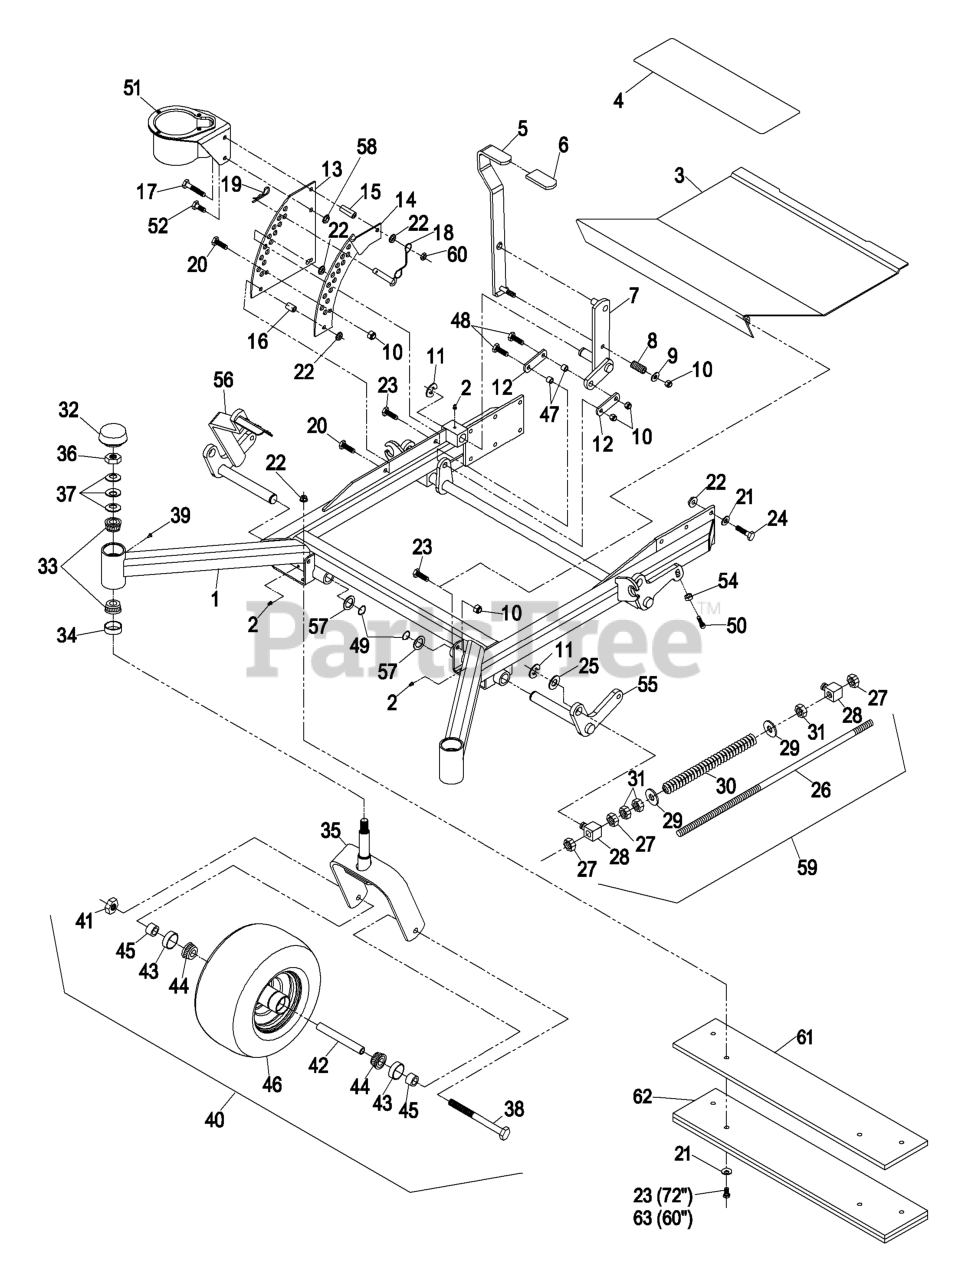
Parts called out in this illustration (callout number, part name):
2	FITTING-GREASE
4	PAD-ANTISKID
5	LIFT LEVER/GRIP ASM
6	GRIP-LEVER, LIFT
7	ARM-LIFT, DECK
8	SPRING-COMPRESSION
9	WASHER-FLAT
10	NUT-LOCK, NI
11	RING-RETAINING, EXT
12	ARM-LIFT, DECK
13	PLATE-LIFT, DECK
14	PLATE-LIFT, DECK
15	BUSHING-LEVER, LIFT
16	BUSHING-LEVER, LIFT
17	SCREW-HH
18	PIN-HITCH (W/LANYARD)
19	PIN-COTTER
20	SCREW-HH
21	WASHER-BELLEVILLE
22	NUT-HHF, WHIZ
23	SCREW-HH
24	SCREW-HH
25	WASHER-FLAT
26	ROD-LIFT, DECK
27	NUT-HEX
28	SWIVEL-DECK MOUNT, REAR
29	WASHER-FLAT
30	SPRING-SUPPORT, DECK
31	NUT-JAM
32	CAP-GREASE
33	Cone-Bearing Tapered Roller
34	SEAL-GREASE
36	NUT-LOCK, NI
37	WASHER-BELLVILLE
38	SCREW-HH
41	NUT-LOCK, NI
42	SPACER-CASTER, FRONT
43	SEAL-CASTER
44	BEARING-CONE, TAPERED ROLLER
45	SPACER-BEARING
47	BUSHING
48	SCREW-HH
49	RING-RETAINING
50	SCREW-HSH
52	SCREW-HH
54	NUT-JAM
55	WLD, FRONT LIFT SHAFT - L
56	WLD, FRONT LIFT W/ LEVER
57	WASHER-SPACER
59	FRONT FRAME SPRING ASM
62	Weight Bar, (60")
63	SCREW-HH
